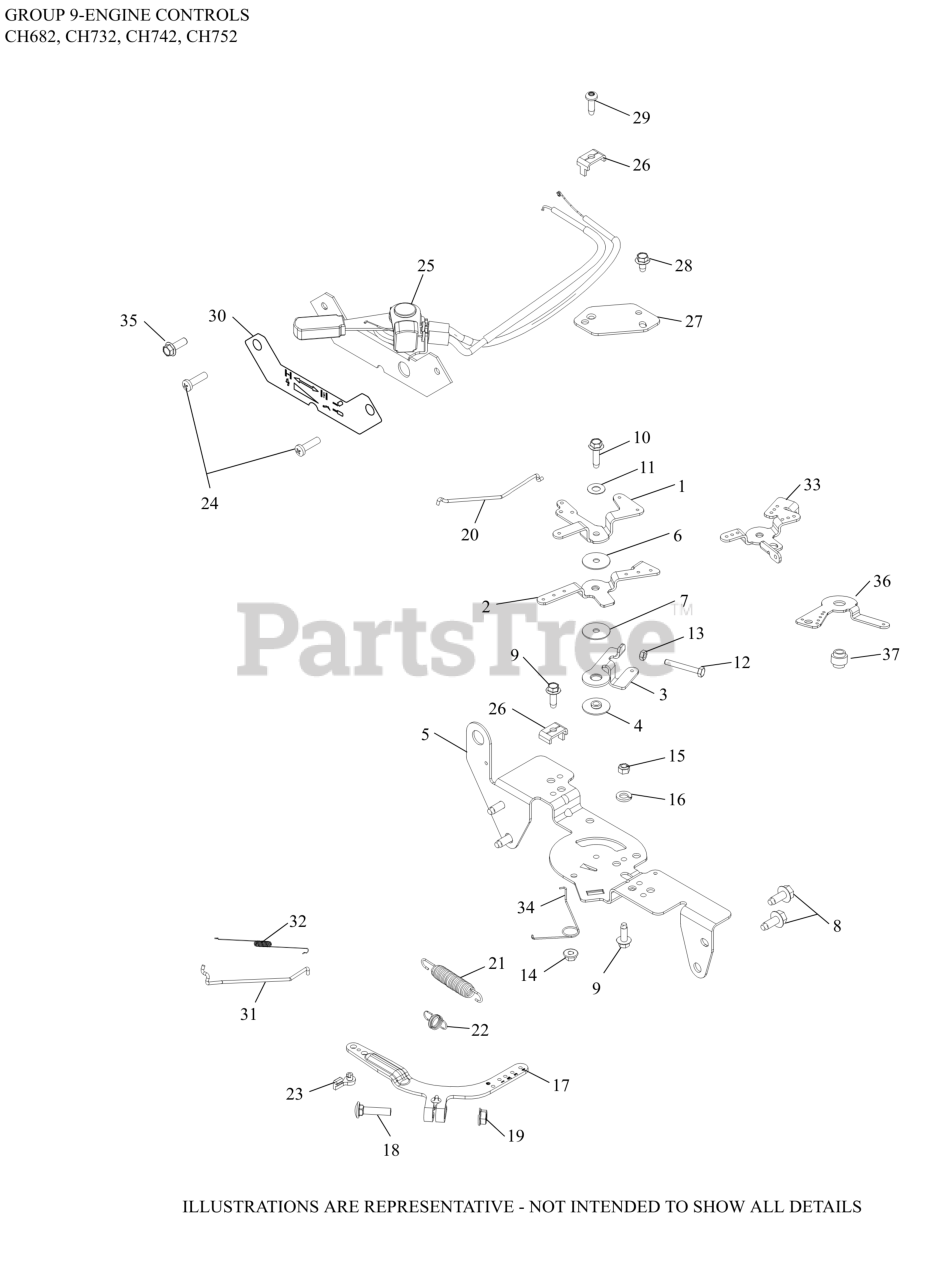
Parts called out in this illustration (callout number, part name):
1	LEVER, CHOKE
2	LEVER, THROTTLE CONTROL
3	LEVER, THROTTLE ACTUATOR
4	SPACER, CONTROL ASSEMBLY
5	BRACKET, CONTROL-(#24126263S)
6	WASHER, FLAT 5.5 MM
7	WASHER, FLAT 5 MM
8	SCREW, THREAD FORMING
9	SCREW, THREAD FORMING
10	SCREW, THD FRM-USE 25 086 473-S
11	WASHER, SPRING 1/4"
12	SCREW, CAP M4X.7X30
13	NUT, M4X0.7
14	NUT, FLG M5X.8
15	NUT, LOCK M5X.8
16	WASHER, SPRING LOCK 1/4"
17	LEVER, GOVERNOR - (#2409069S)
17	LEVER, GOVERNOR ASSEMBLY
18	BOLT, RD HD SQ NECK M6X1.0X25
19	NUT, FLG M6X1.0
20	LINKAGE, CHOKE
21	SPRING, GOVERNOR (RED)
22	SPRING, GOVERNED IDLE
23	BUSHING, THROTTLE LINKAGE
25	CABLE, CONTROL ASSEMBLY
26	CLAMP, CABLE
27	BRACKET, CABLE SUPPORT
28	SCREW, THREAD FORMING
29	SCREW, THREAD FORMING
30	DECAL, CONTROL PANEL
31	LINKAGE, THROTTLE
32	SPRING, LINKAGE
35	SCREW, HI-LOW
